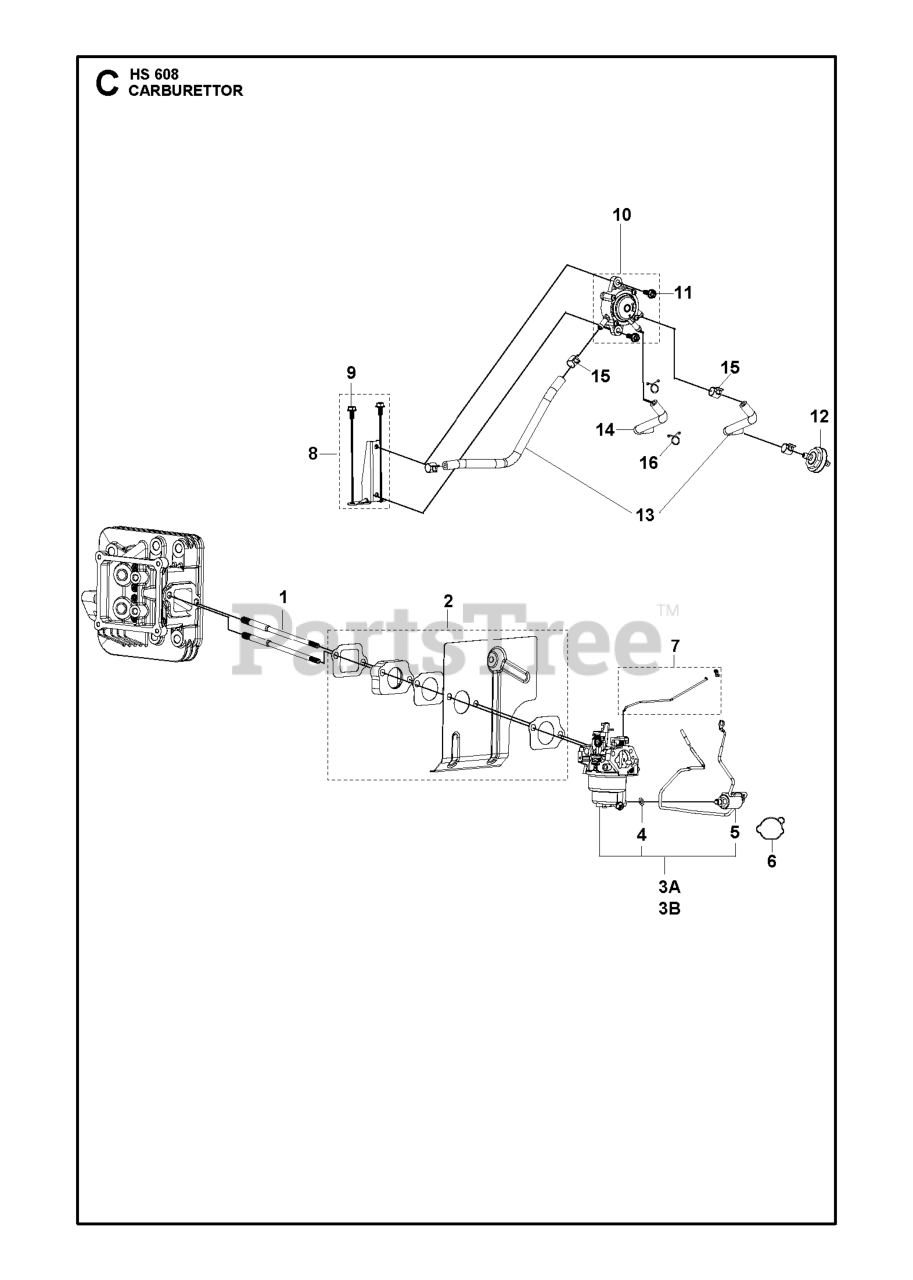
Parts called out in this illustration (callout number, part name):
1	STUD T430: M8/6 L=147
2	GASKET KIT CARBURETTOR GASKET
3B	CARBURETTOR
5	SOLENOID SOLENOID VALVE
6	GASKET CARBURETTOR GASKET
7	CHOKE ROD KIT
8	BRACKET FUEL PUMP BRACKET
9	BOLT GB/T 5789: M6 L=12
10	FUEL PUMP FUEL PUMP.
11	Husqvarna TBD
12	FILTER FUEL.FILTER (ENG.452)
13	TUBE
14	TUBE
15	CLIP HOSE CLIP
16	CLIP HOSE CLIP
